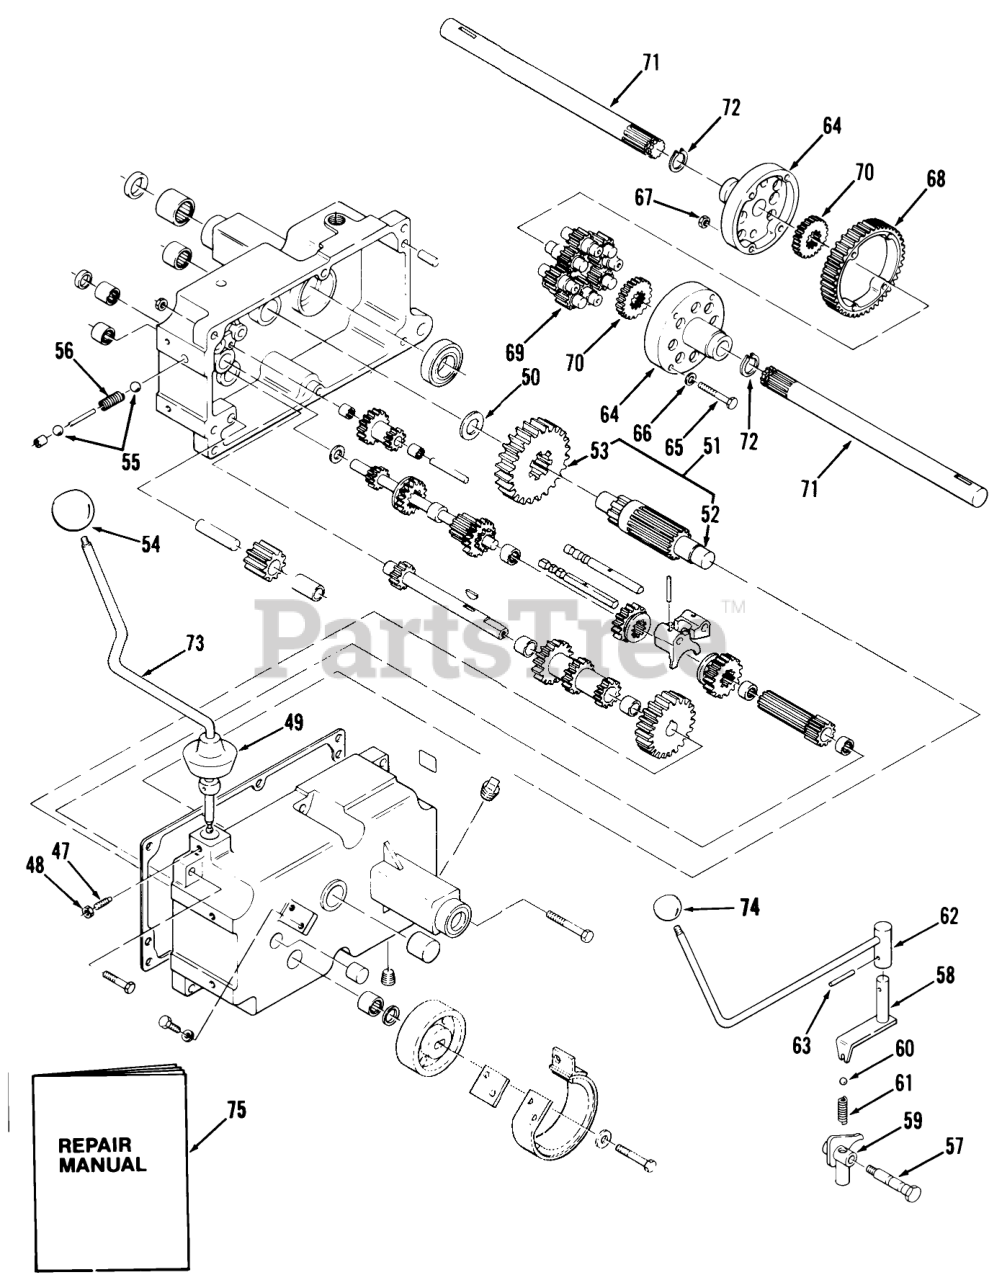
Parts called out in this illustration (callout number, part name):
13	SEAL-OIL
47	SETSCREW
48	Nut
49	COVER-DUST
50	WASHER-THRUST
51	GEAR ASM
52	PINION SHAFT
55	BALL-DETENT
56	SPRING-SHIFT STOP
57	BOLT-DETENT
58	SHIFT ASM
59	Shift Fork
60	BALL-DETENT
61	SPRING-SHIFT STOP
62	Shift Lever HI-Low Range
63	PIN-SPIROL
64	DIFFERENTIAL END CAP
65	BOLT-HEX
66	WASHER
68	GEAR-DIFFERENTIAL RING, 43T
69	GEAR-PINION, 11T
70	GEAR-AXLE DIFFERENTIAL
71	AXLE-REAR
72	RING-SNAP
73	Gear Shift Lever
74	Knob
75	MANUAL
